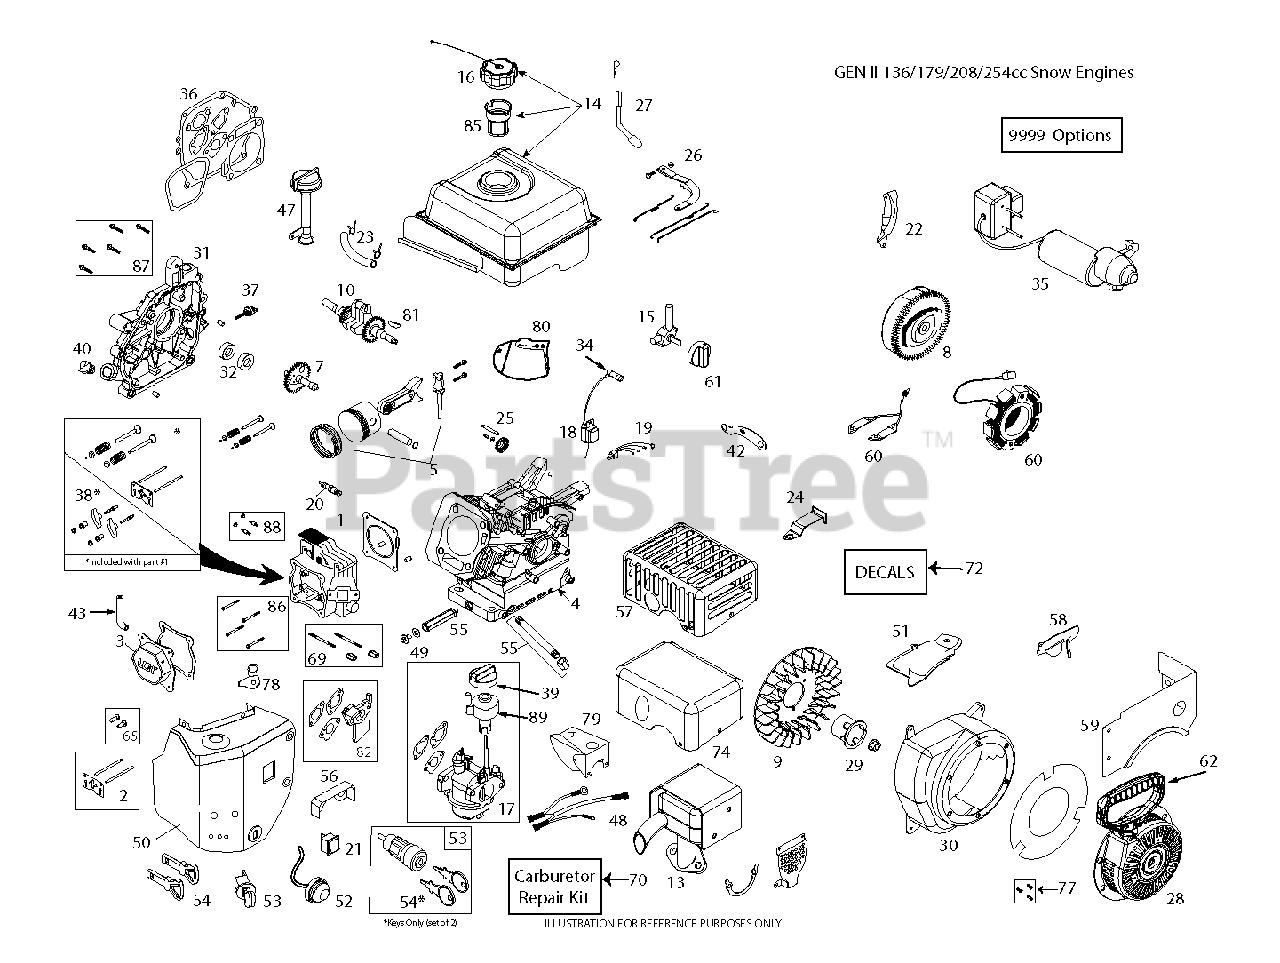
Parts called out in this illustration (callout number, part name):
1	CYLINDER HEAD LCT 178 INCLUDES
2	KIT.PUSH.ROD.SRV(SK208-1001)
3	VALVE COVER LCT 179/208
4	CYLINDER ASSY LCT 179
5	PISTON & ROD ASM LCT 136
7	CAMSHAFT MCR LCT 179 INCLUDES
8	FLYWHL.ASSY.MANUL.SK2081700
9	KIT.COOLNG.FAN.SERV(SK208-4000
10	CRANKSHAFT KEYED LCT 179
13	MUFFLER KIT LCT 179
14	FUEL.TK.ASSY.GENII.SKSN0311.1
15	FUEL.PETCOCK.SNOW(SKSN4900)
16	FUEL CAP OVERSIZED CLICK STYLE
17	CARBURETTOR L17D GEN 2 LCT 179
18	208CC IGN COIL (STD)
20	SPARK.PLUG(2083810)
22	FLYWHEEL SHIELS.LCT 136 MANUAL
23	FUEL HOSE KIT
24	BRACKET SPEED CONTROL LCT
25	GOVENOR.GEARS ASM(SK2082900)
26	ARM.ASM.GOVNR.LCT.136CC
27	SHAFT.ASM.GVNR.LCT13631001
28	RECOIL.ASSY(HEX-BLACK)SNOW
29	STARTER.CUP.SMALL(SKSN-0601.1)
30	BLOWER HOUSING LCT 179
31	Husqvarna TBD
32	SEAL KIT (2 PCS)
34	SPARK.PLUG.BOOT.SNW,SKSN4691.1
36	KIT.GASKET.LCT.136CC
37	DIPSTICK SMALL
38	KIT ROCKER.ARM.LCTSK13611001
39	CHOKE.KNOW.SNOW(SKSN4500)
43	TUBE.BREATHER.LCT.208
47	TUBE HIGH OIL FILL LCT 179
48	WIRE.HARNESS.SNOW
49	KIT.OIL.DRAIN.PLUG(SK2089911
50	HEATER.BOX.ASY-GEN2
51	SHIELD.CYLINGER.LCT.SKSN0608.1
52	PRIMER.BULB.WITH HOSE (SNOW)
53	KEY SWITCH ROTARY.LCT.W/2 KEYS
54	KEY SET.ROTARY.LCT
55	OIL PIPE DRAIN LCT 254
57	MUFFLER SHIELD LCT CE COMP 136
58	GOVERNOR SHIELD LINKAGE LCT
59	FUEL.TNK.SKRT.GENII.SKSN0103.1
61	FUEL KNOB-SNOW
62	STARTER.GRIP.SNOW.LCT.SKSN0603
65	TAPPET KIT.LCT.SK1361005.1 136
69	CARB.STUDS & COUPLING KIT.SNOW
70	CARB.REPAIR.KIT.LCT.SK9900.2
72	ARIENS 136CC PW7 (ALL) DECAL
74	MUFFLER COVER HEAT SHIELD LCT
77	BOLT.KIT.RECOIL.LCT.ALL.ENGINE
79	COVER.CARBURETOR.SNOW
80	SHIELD TOP LCT 179
81	Husqvarna TBD
82	SPACER.CARBURETOR.136CC.LCT
85	DECAL.HOOD.RH.
86	KIT.BOLT.CYLINDER.HEAD.(4PC)
87	KIT.BOLT.CRANKCASE.COVER.136CC
88	STUD.MUFFLER.KIT.LCT
9999	HIGH.ALTITUDE.JET.(>6,000FT)
